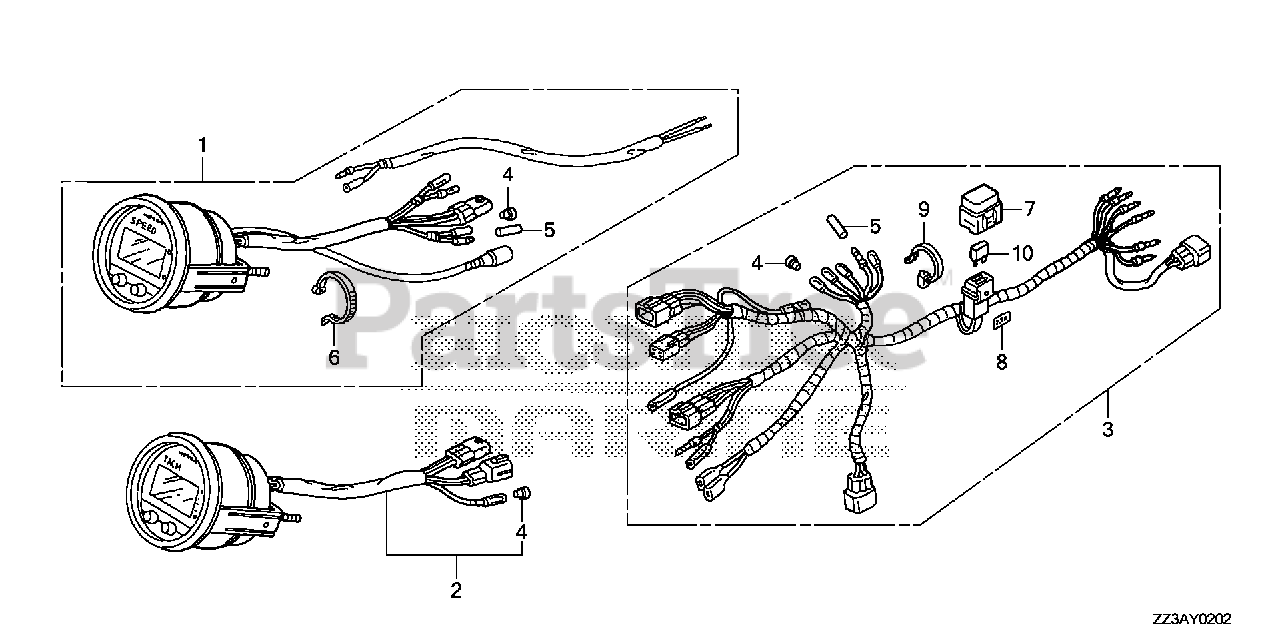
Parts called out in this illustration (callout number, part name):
1	SPEEDOMETER KIT (DIGITAL)(USA)
2	METER KIT, TACHO (DIGITAL) (USE FOR 32540-ZY3-802)
3	HARNESS ASSY., METER (A)(DIGITAL)
4	PLUG, CONNECTOR (INNER)
5	PLUG, CONNECTOR (OUTER)
6	BAND (BLACK 3.5X140)
7	COVER ASSY., FUSE (7.5A)
8	MARK, FUSE (7.5A)
9	TIE, CABLE
10	FUSE, BLADE (7.5A)
